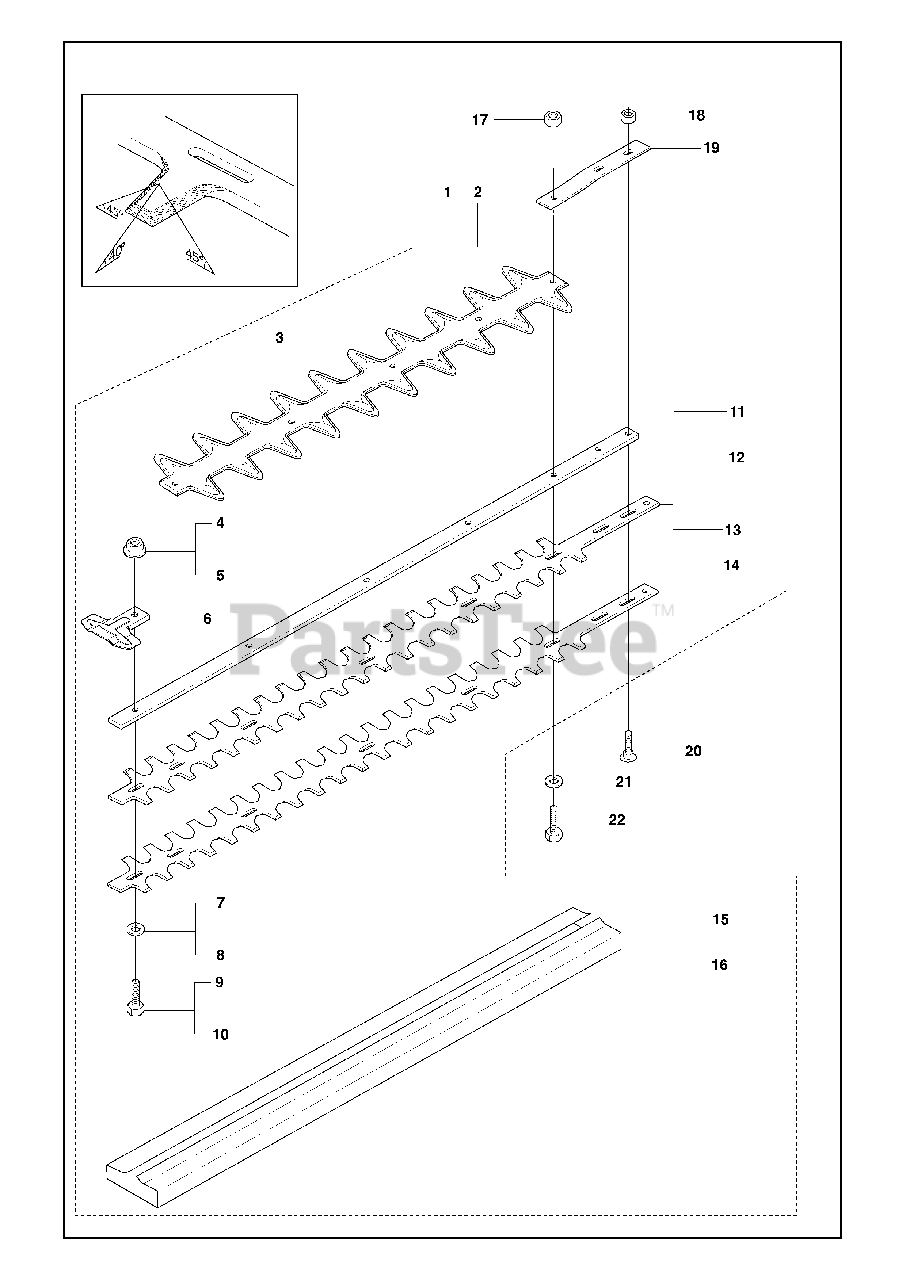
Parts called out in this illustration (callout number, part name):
1	GEAR HOUSING
2	BALL BEARING 6002-2RS1
6	GREASE NIPPLE
7	CLUTCH YOKE
8	CLUTCH CPL
12	CLUTCH DRUM
13	SCREW W/ LOCKING FLUID
27	CONNECTING ROD
30	BALL BEARING
31	WASHER 15X24
